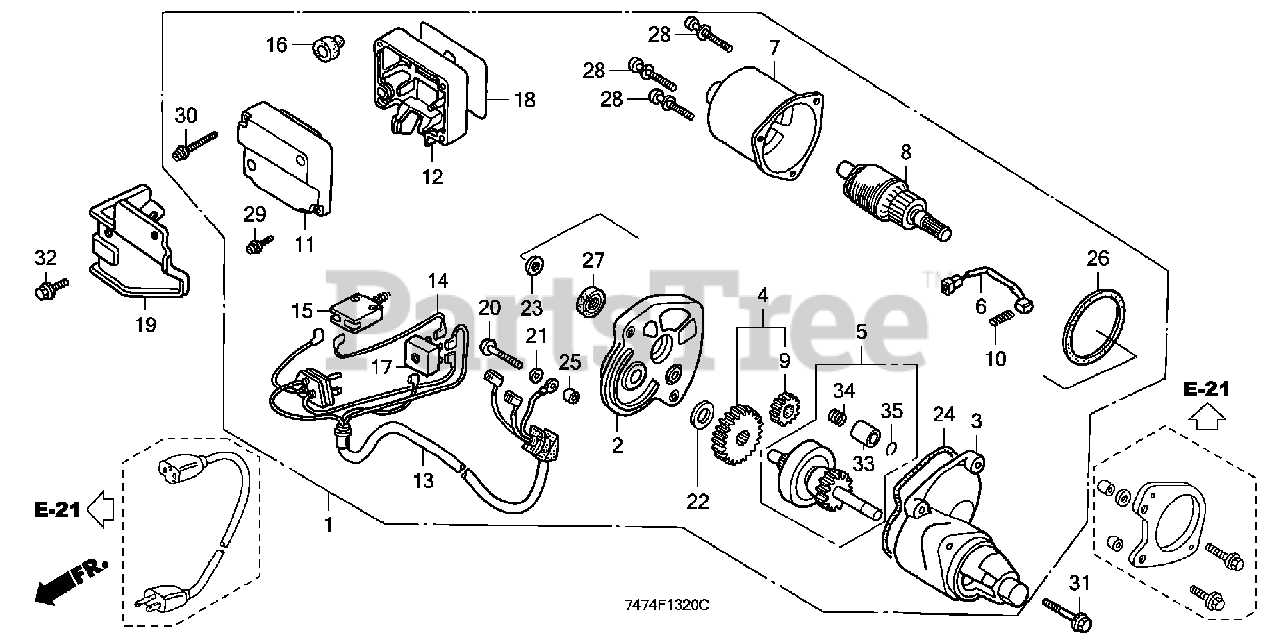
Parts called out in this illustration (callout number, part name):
1	MOTOR ASSY., STARTER
2	HOUSING, CENTER
3	HOUSING, PINION
4	GEAR, REDUCTION
9	GEAR, DRIVE
10	SPRING, BRUSH RETURN
15	SWITCH, STARTER (A.C. 380V-16A)
15	SWITCH, STARTER (A.C. 250V-16A)
18	PLATE, CAUTION (ENGLISH)
19	BRACKET, SWITCH BOX
20	SCREW, TRUSS (4X30)
21	WASHER, STAR (4MM)
22	WASHER (A)
23	WASHER (B)
28	SCREW-WASHER (5X30)
29	SCREW-WASHER (4X20)
30	SCREW-WASHER (4X30)
31	BOLT, FLANGE (6X20)
32	BOLT, FLANGE (6X40)
33	STOPPER, PINION
34	SPRING, COIL
35	RING, RETAINING
